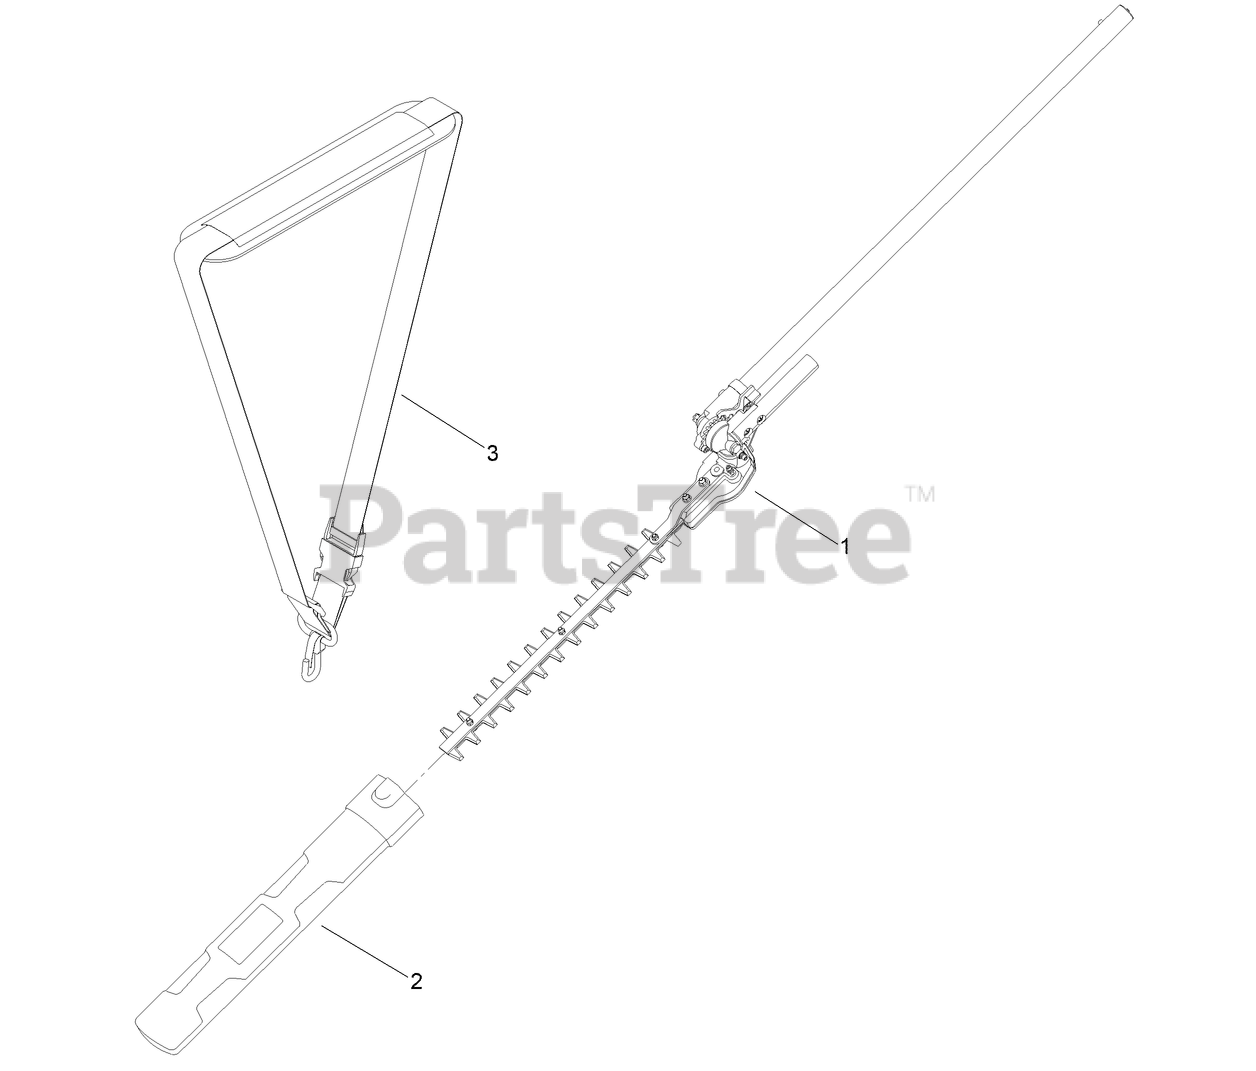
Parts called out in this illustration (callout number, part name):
1	TRIMMER-HEDGE
2	GUARD-TRIMMER, HEDGE
3	SHOULDER STRAP
